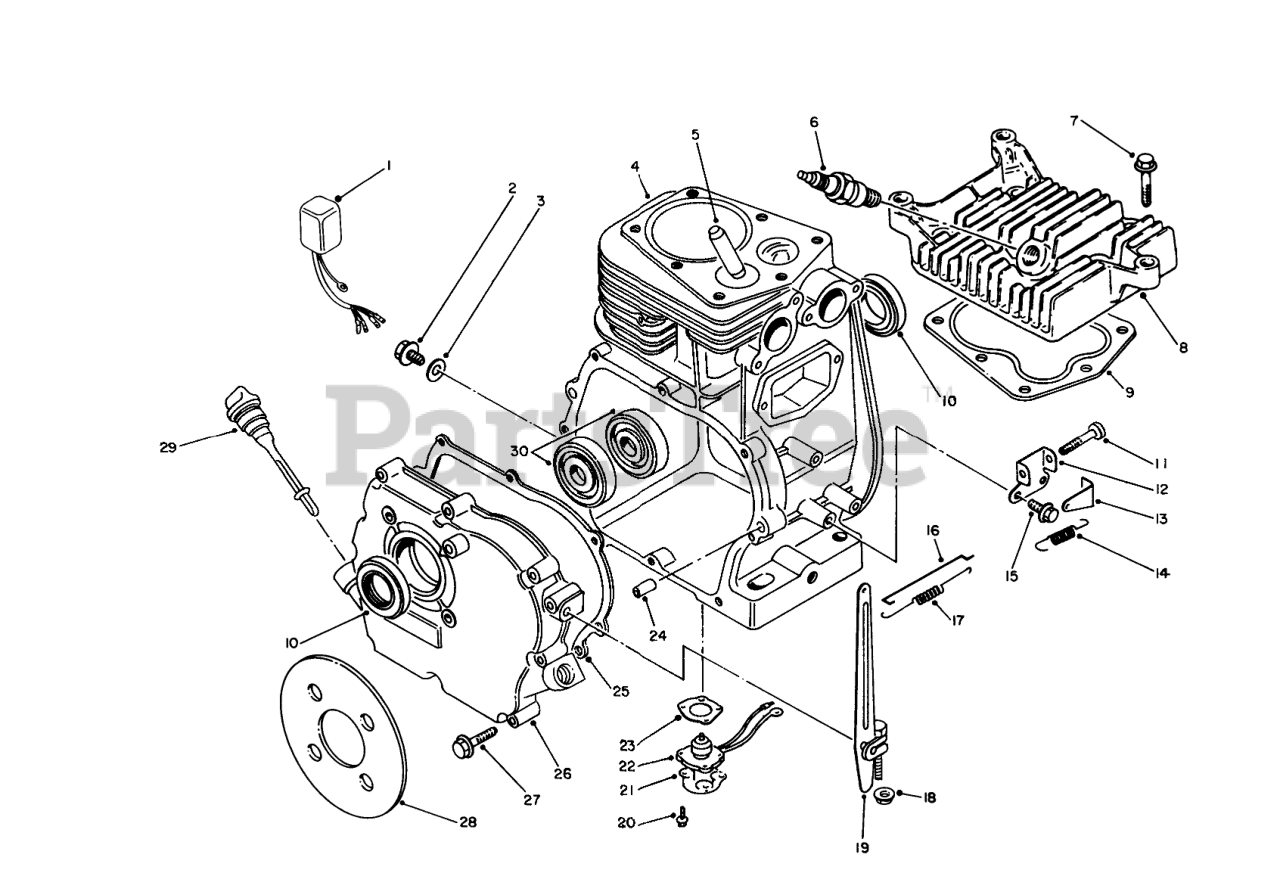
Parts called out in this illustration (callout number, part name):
1	OIL LEVEL UNIT
2	Drain Plug
3	GASKET
4	Cylinder
5	VALVE GUIDE
6	SPARK PLUG
8	Cylinder Head
9	GASKET
10	Oil Seal
12	Bracket
14	SPRING
15	Bolt
16	Rod-Carburetor
17	SPRING
19	Lever-Control
21	Plate
22	SENSOR
23	GASKET
25	Gasket-Crankcase
26	Cover-Crankcase Side
28	Seat-Joint
29	Gauge-Oil Level
30	Bearing
